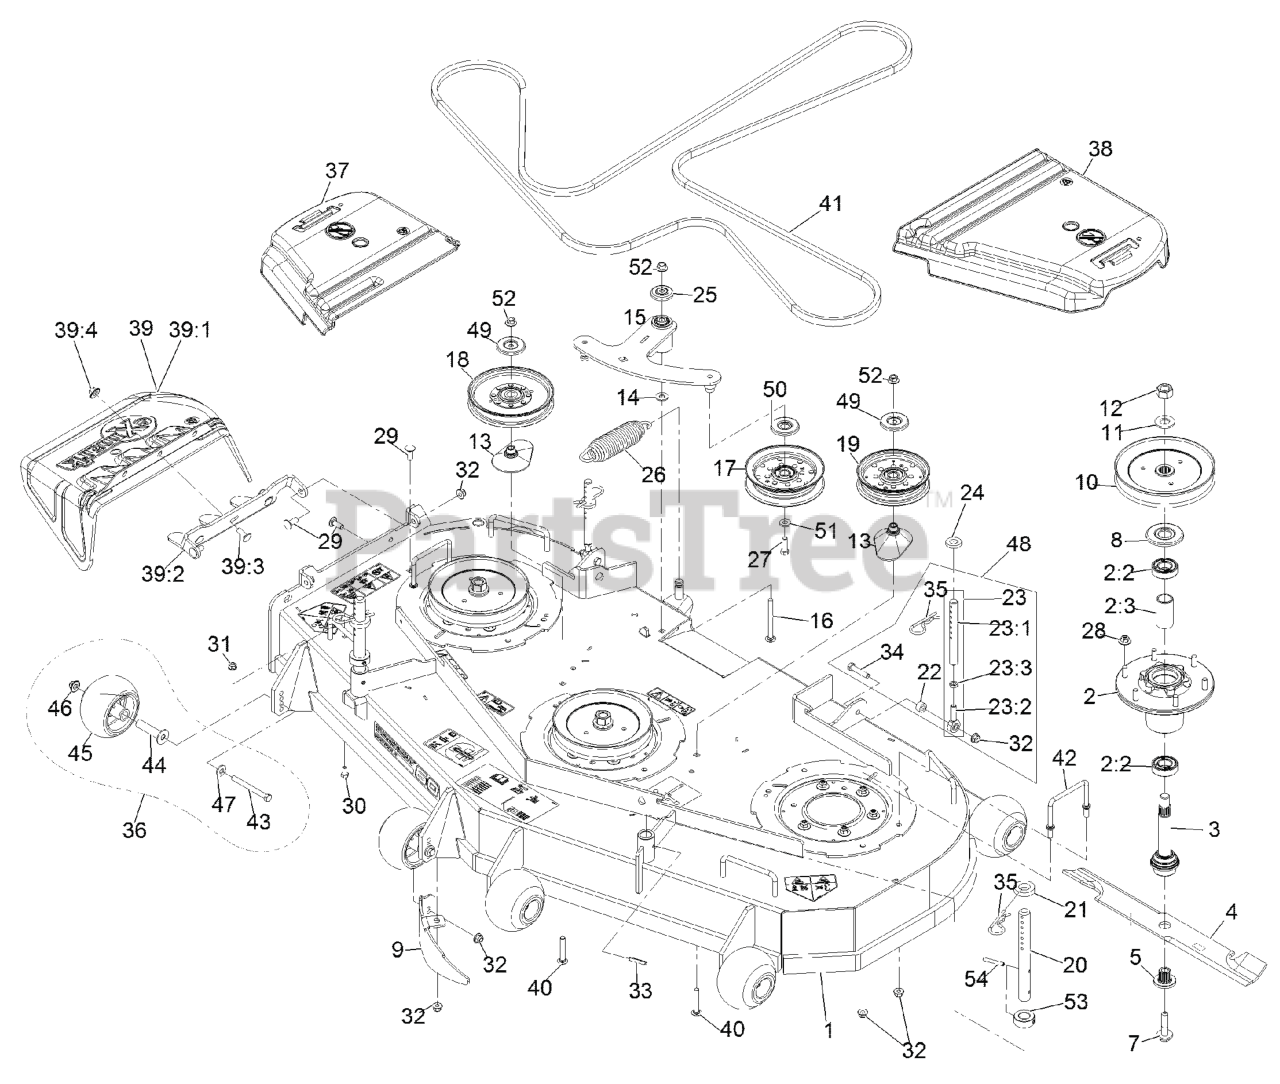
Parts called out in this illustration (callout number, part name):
1	ASM, DECK W/ DECALS, 60"
2	ASM-CUTTER HSG WITH BEARINGS
2:2	BEARING-BALL
2:3	SPACER-BEARING
3	ASM-SPINDLE AND SEAL
4	Blade-Extreme 2, 20.50"
5	BUSHING,SPLINED
7	SCREW,SEMS 1/2-20 X 2.19
8	GUARD,BEARING TOP .989
9	DOGLEG - LZ60
10	SHEAVE,BLADE DRIVE 7.25
12	NUT-HEX
13	SPACER-PULLEY
14	WASHER-FLAT
15	ASM, DECK IDLER
16	SCREW-CARR
17	IDLER-PULLEY, FLAT
18	IDLER-PULLEY
19	PULLEY-IDLER, FLAT
20	Rod, Deck Support
21	SPACER-DECK SUPPORT
23:1	LINK,SUPPORT
23:2	BALLJOINT
23:3	NUT-HJ
25	GUARD-TOP
26	SPRING-EXTENSION
27	SCREW-HH
28	Nut-Nyloc 3/8-16 Flg
29	SCREW-CARR
30	SCREW-HH
31	NUT-HF, NI
32	NUT-HF, NI
34	SCREW-HH
35	PIN,HAIR COTTER
36	KIT, ANTI-SCALP ROLLER
37	COVER-BELT, RH
38	COVER-BELT, LH
39	ASM,DISCHARGE CHUTE
39:1	CHUTE,DISCHARGE
39:2	BRACKET,DISCHARGE CHUTE
39:3	SCREW-CARR
39:4	Nut-Nyloc 3/8-16 Flg
40	BOLT-CARR, SHORT NECK
41	BELT, DECK DRIVE
42	WIREFORM-COVER
43	SCREW-HH 3/8-16 X 3 3/4 GR 8
44	AXLE, ROLLER
45	ROLLER-SCALP, ANTI
46	Nut-Nyloc 3/8-16 Flg
47	WASHER-BELLEVILLE
48	KIT,SUPPORT LINK W/PIN
49	SHIELD-DUST
50	SHIELD-GUARD, DUST
53	Collar, Deck Height Pin
54	PIN-ROLL
